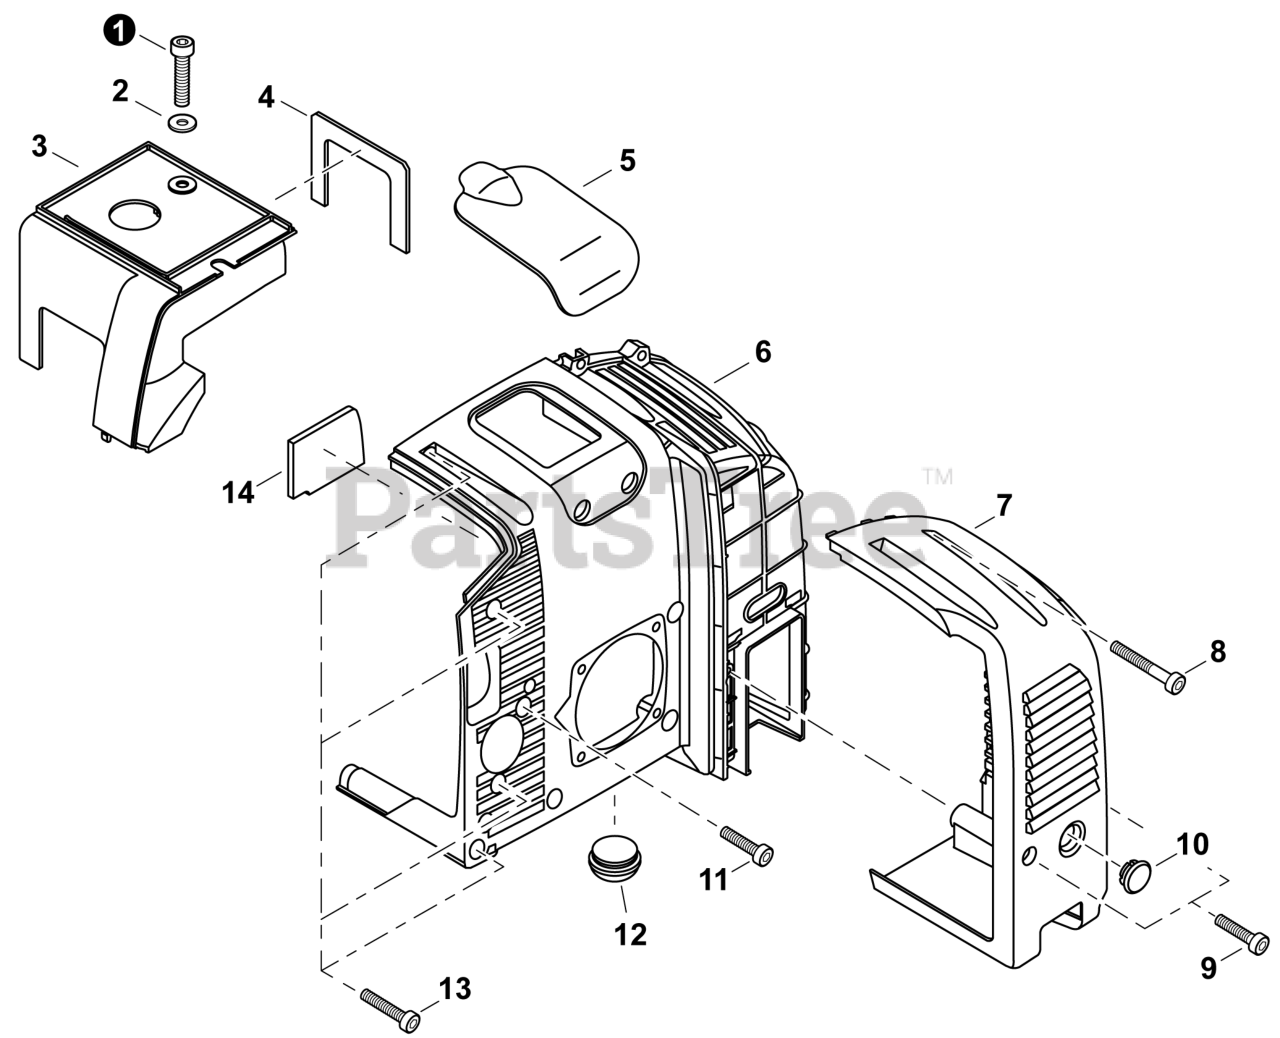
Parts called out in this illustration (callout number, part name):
1	BOLT 5x20
2	WASHER 5.2x14xT3
3	COVER, CYLINDER
4	PLATE, INSULATOR
5	COVER, SPARK PLUG
6	COVER, ENGINE
7	COVER, MUFFLER
8	BOLT, TORX 5x25
9	BOLT, TORX 5x16
11	BOLT, TORX 5x16
12	CUSHION
13	BOLT, TORX 5x20
14	PLATE, INSULATOR
